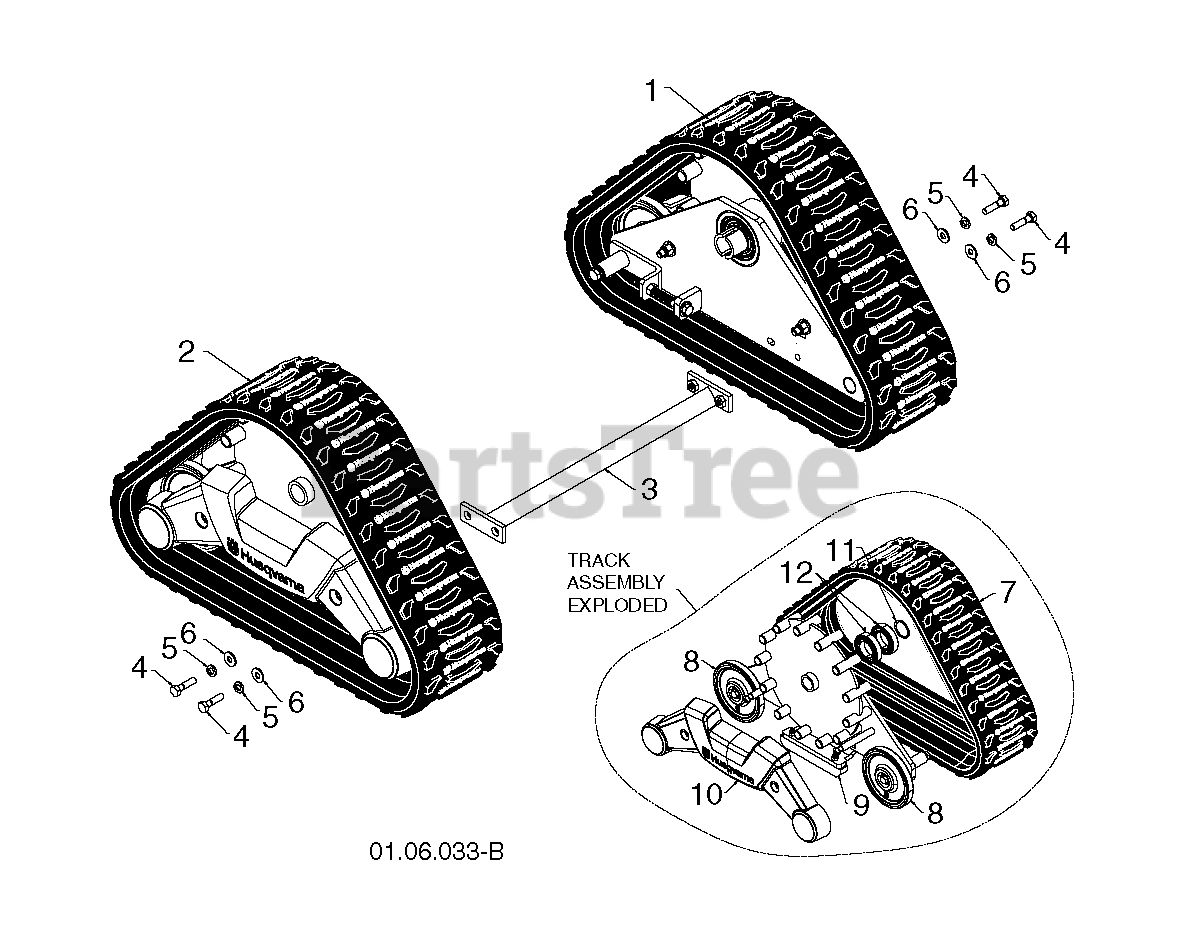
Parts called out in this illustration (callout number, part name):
1	WHEEL.ASM.TRACK.LH.12.SNOW
2	WHEEL.ASM.TRACK.RH.12.SNOW
3	SUPPORT.BRACE.ASM.TRACK.12
4	BOLT.5/16-18X1-1/4 FULL.THREAD
5	LOCKWASHER
6	WASHER
8	WHEEL.IDLER.TRACK.SNOW
9	GUIDE.TRACK.SNOW
10	COVER.SIDE.TRACK
11	Snap Ring, 1.25
12	BEARING.BALL.SHIELD.TRACK.SNOW
